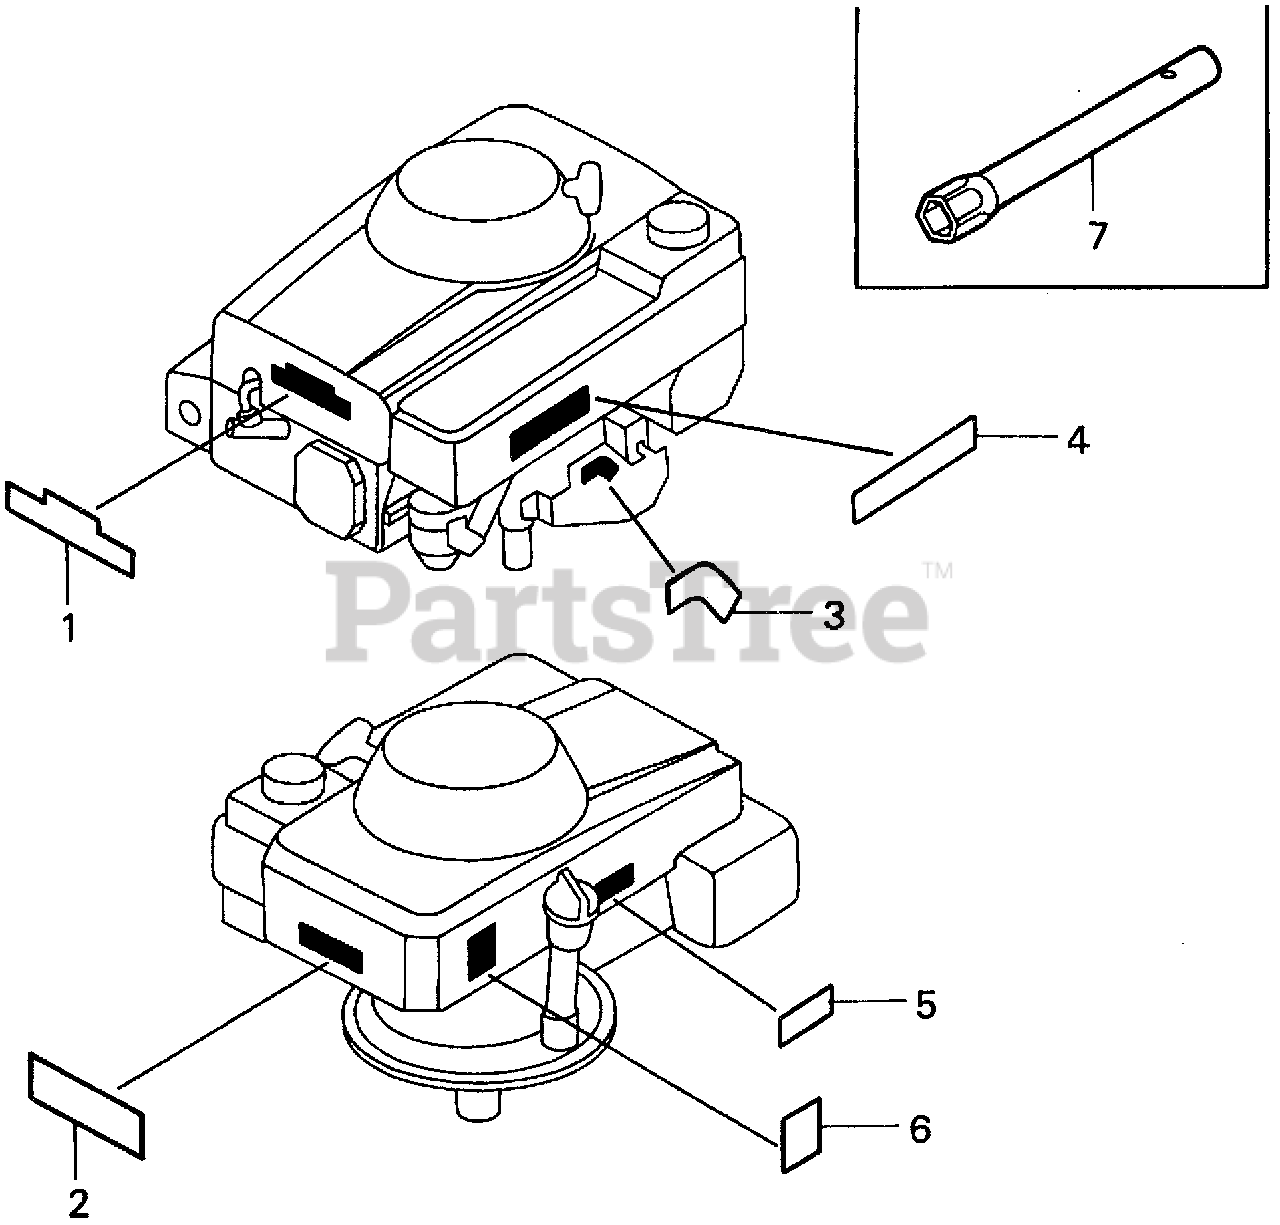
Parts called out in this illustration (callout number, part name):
1	MARK, TOP COVER EMBLEM
2	MARK, CAUTION (H)
3	MARK, CONTROL
4	LABEL, AIR CLEANER CAUTION (H)
5	MARK, BRAKE CAUTION
7	WRENCH, BOX (P21)
8	LABEL, FUEL CAUTION
